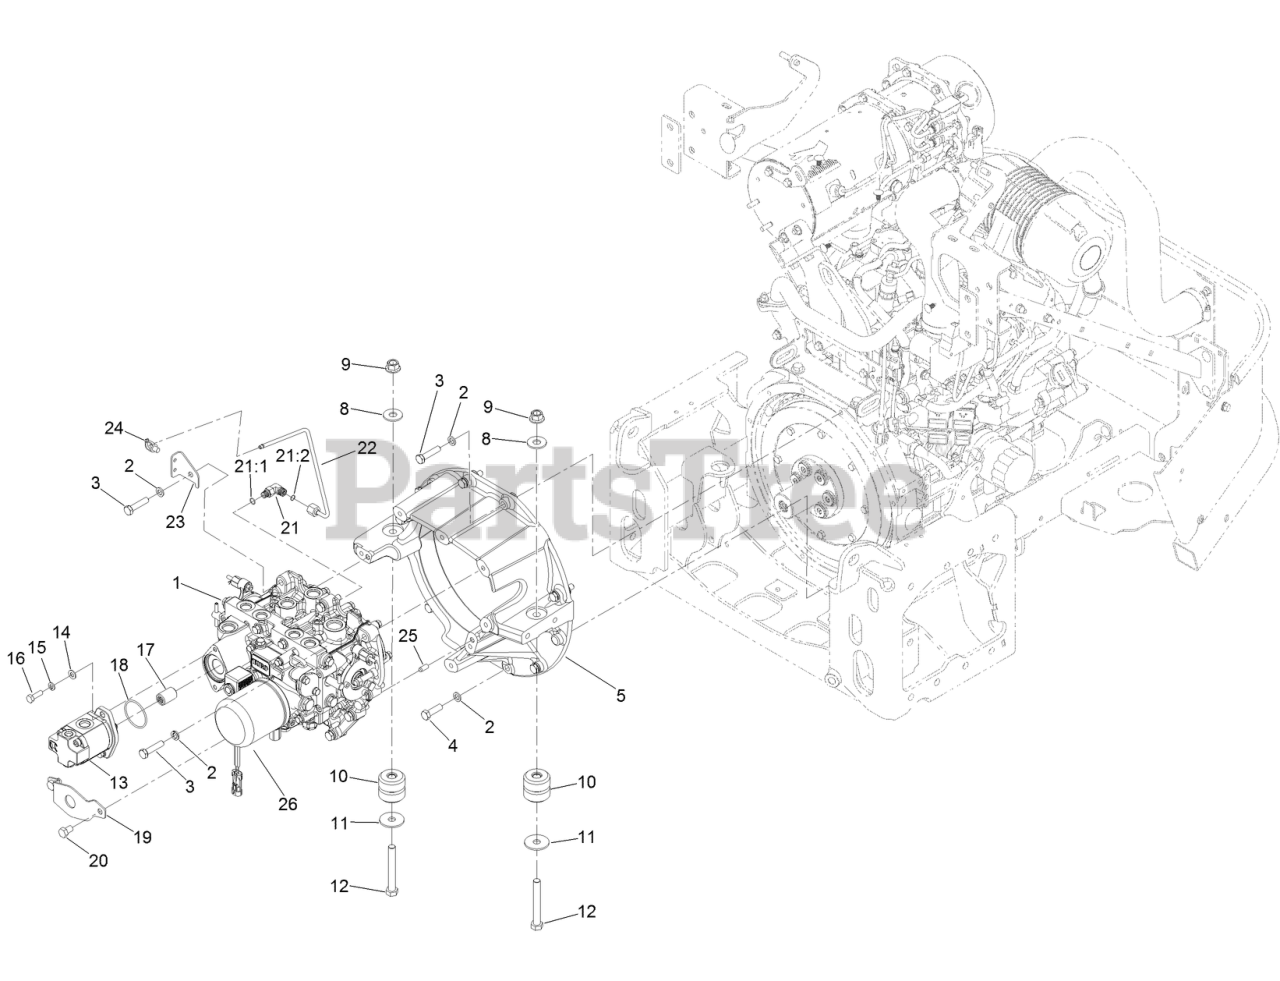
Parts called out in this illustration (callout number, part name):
1	TRANSMISSON ASM
2	WASHER-LOCK
3	SCREW-HH
4	SCREW-HH
5	HOUSING-FLYWHEEL
8	WASHER-FLAT
9	NUT-LOCK
10	MOUNT-ISOLATOR
11	WASHER-THRUST
12	SCREW-HH
13	HYD GEAR PUMP ASM
14	WASHER-PLAIN
15	WASHER-LOCK
16	SCREW-HH
17	COUPLER-SPLINE
18	O-RING
19	SHIELD-SEAL
20	SCREW-HH
21	FITTING-ELBOW, 90 DEG
21:1	O-RING
21:2	O-RING
22	TUBE ASM
23	SUPPORT-TUBE
24	CLIP-TIE
25	PIN-DOWEL
26	FILTER-OIL, HYD
